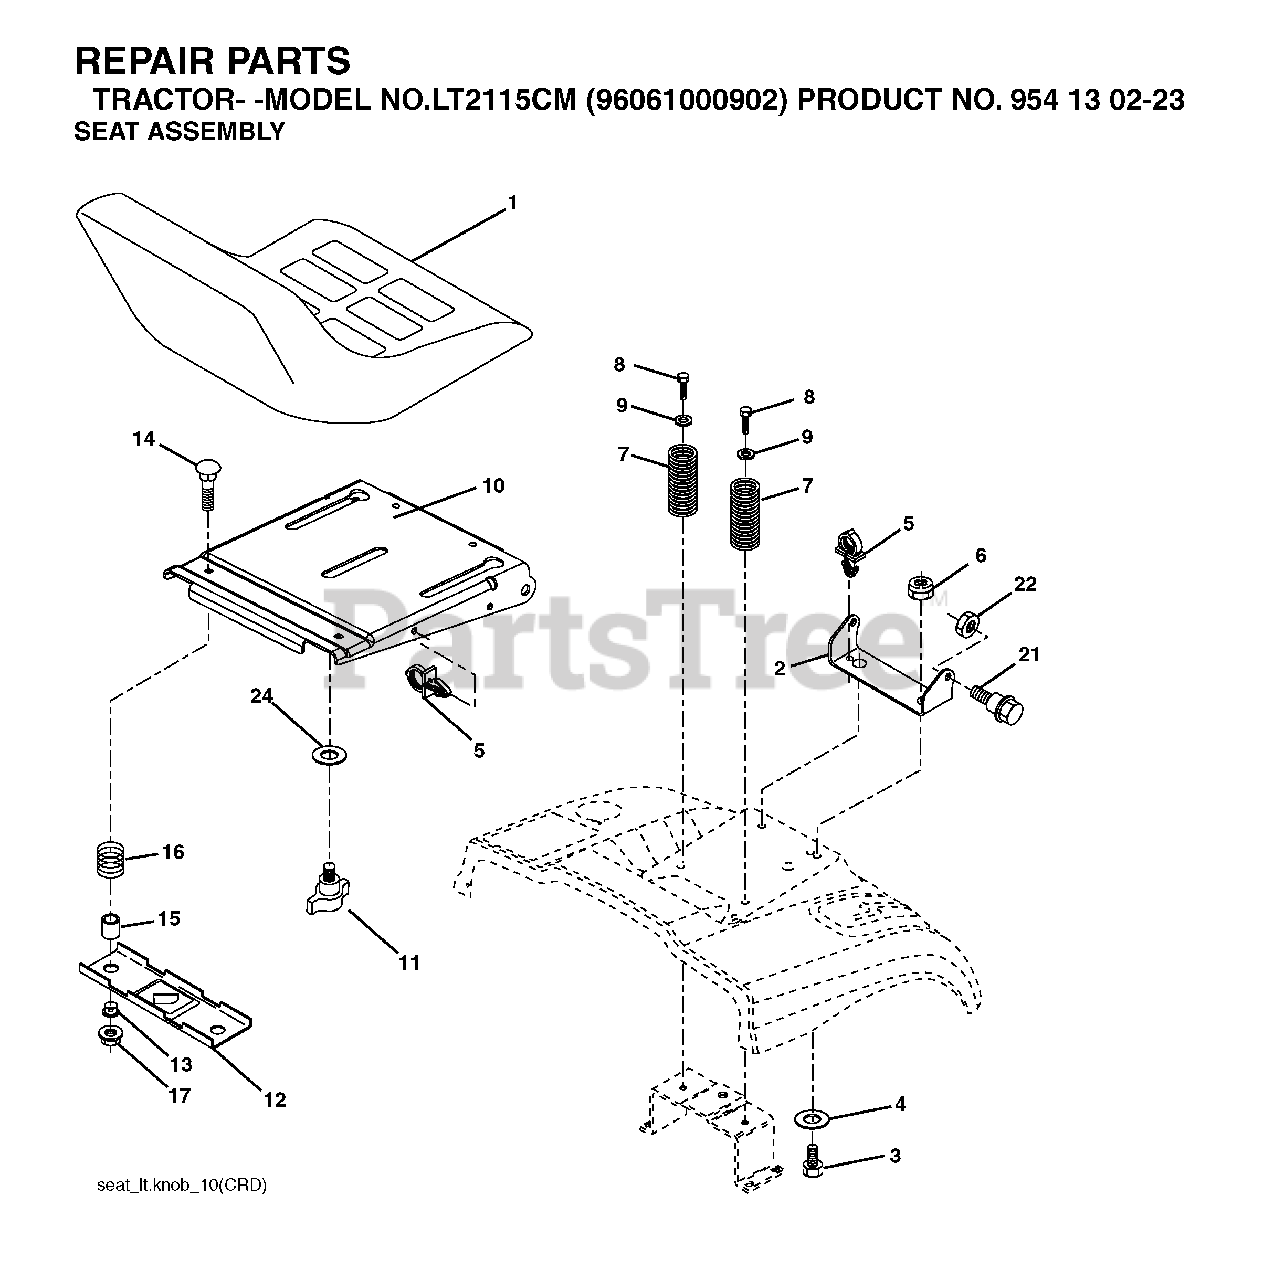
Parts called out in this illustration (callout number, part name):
2	BRKT.PIVOT.FENDER
4	WASHER PM
5	PUSH CLIP
6	NUT
7	SPRING COMPRESSION
8	SCREW 3/8-16X1
9	WASHER
11	KNOB.SEAT.ADJ.WINGNUT
12	BRKT SWITCH
14	BOLT.ROUND.HEAD.SQUARE.NECK
15	SPACER SPLIT 28X.96
17	NUT T
21	BOLT.SHOULDER.5/16-18
22	NUT.71038.31-18.HEX.NYLOCK
